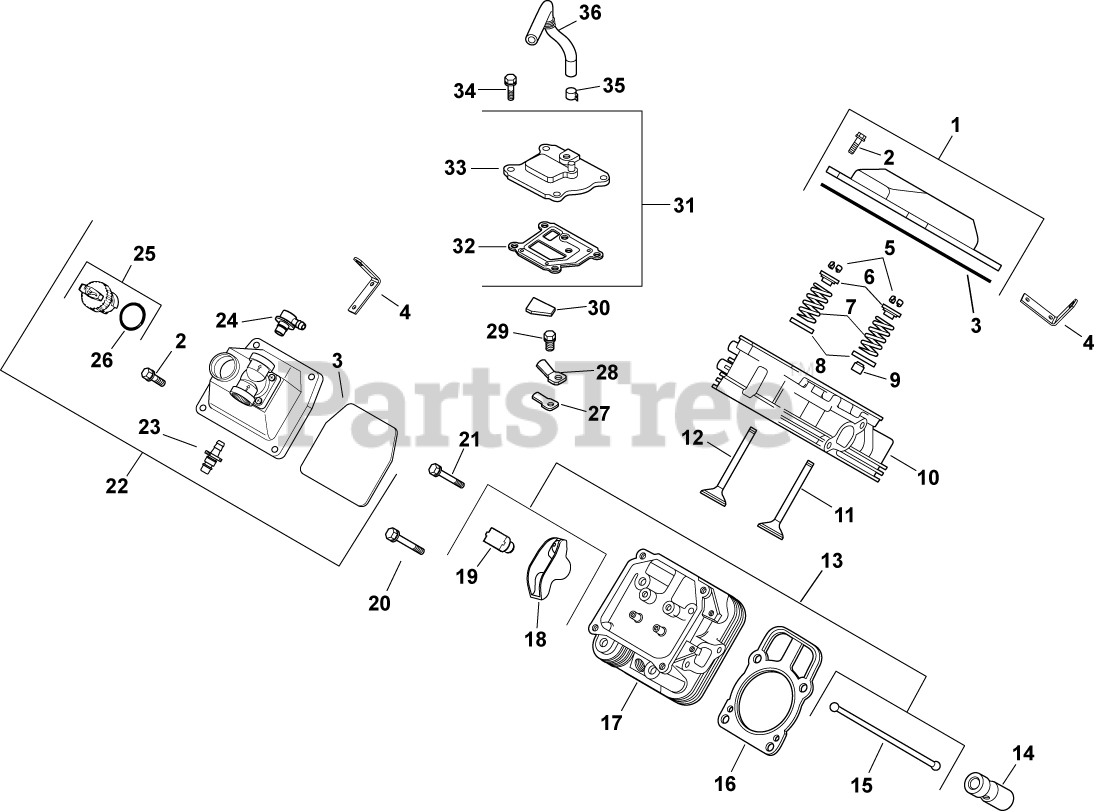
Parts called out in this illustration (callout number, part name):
1	KIT, VALVE COVER-PLAIN
2	SCREW, FLG M6X1.0X30
3	O-RING (YELLOW) -USE 24 153 30-S
4	STRAP, LIFTING-USE 25 445 03-S
5	KIT, RETAINER
6	RETAINER, VALVE SPRING - USE 25 173 28-S
7	SPRING, VALVE
8	RETAINER, SPRING
9	SEAL, VALVE STEM - (#2503214S)
10	HEAD, ASSEM CYLINDER #1 -USE 24 318 107-
11	VALVE, INTAKE (STD)
12	VALVE, EXHAUST (STD) - USE 32 016 01-S
13	KIT, VALVE TRAIN
14	LIFTER, HYDRAULIC VALVE-USE 25 351 10-S
15	ROD, PUSH
16	KIT, CYL HEAD GASKET (C17-22)
17	HEAD, ASSEM CYLINDER #2 -USE 24 318 115-
18	ARM, ROCKER
19	PIVOT, ROCKER ARM
20	SCREW-USE 62 086 08-S
21	SCREW, FLG M6X1.0X34
22	KIT, VALVE COVER-FUEL PUMP
23	KIT, 90 DEG. FITTING
24	KIT, STRAIGHT FITTING
25	CAP ASSY, OIL FILL (YELLOW)
26	O-RING-USE 24 153 32-S
27	REED, BREATHER
28	RETAINER, REED
29	SCREW, FLG THD FRM M5X.8X10
30	FILTER, BREATHER-USE 24 050 11-S
31	KIT, BREATHER ASSEMBLY
32	GASKET, BREATHER-USE 24 041 67-S
33	COVER, BREATHER -USE 24 033 01-S
34	SCREW,FLG THD FRM M6X1.0X20-(#25086396S)
35	CLAMP, HOSE 1/2" USE 25 237 14-S
36	HOSE, BREATHER-USE 24 326 89-S
2401602-S	VALVE, EXHAUST (.25)
2401702-S	VALVE, INTAKE (.25)
2404101-S	GASKET, INTAKE MANIFOLD USE 24 041 79-S
2404149-S	GASKET, EXHAUST
2507204-S	STUD, EXHAUST (KM)-USE 25 072 24-S
2514106-S	TOOL, INSTALLATION (SNAP RING)
2535714-S	Lubricant, Camshaft/Lifter (0.25 oz.)
24755147-S	KIT, CYLINDER HEAD HARDWARE
